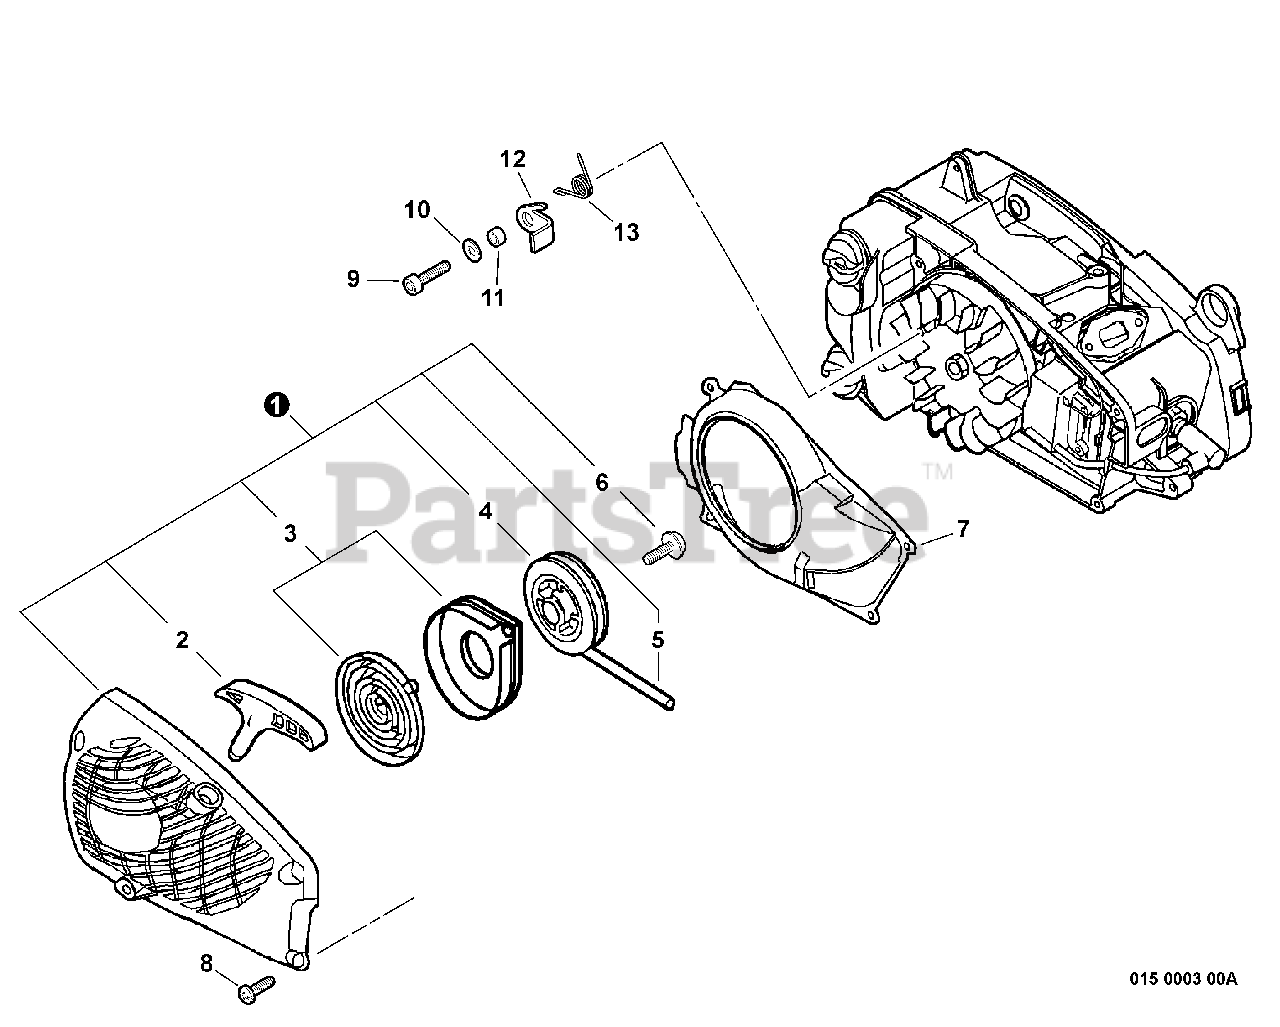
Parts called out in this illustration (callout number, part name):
1	STARTER ASSY - GRAY
2	GRIP, STARTER
3	REWIND SPRING ASSY
4	REEL, ROPE
5	ROPE, STARTER - 3X920
7	COVER, FAN
9	SCREW - 5X14
10	WASHER - 5
12	PAWL, STARTER
13	SPRING, RETURN
